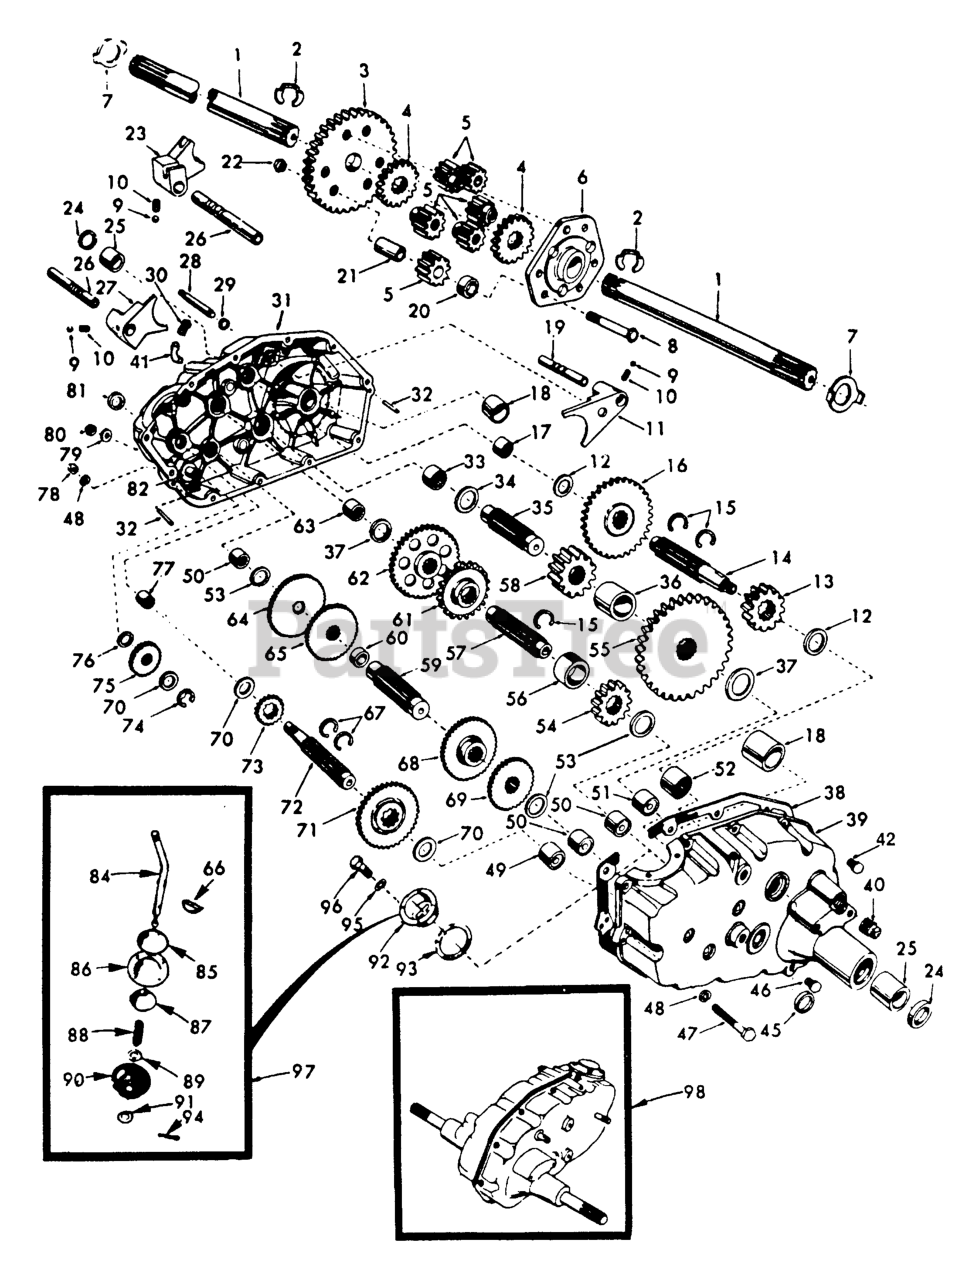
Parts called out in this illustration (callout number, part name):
1	AXLE SHAFT T
2	Retaining, Ring
3	FINAL GEAR T
4	DIFF GEAR T
5	DIFF PINION T
6	DIFF CARRIER T
7	WASHER T
8	Hex, Bolt 3/8-24 x 3-1/4 (1" Thread Length)
9	STEEL BALL KIT
10	SPRING T
12	THRUST WASHER
13	RED PINION T
14	GEAR SHAFT T
15	SNAP RING T
16	GEAR T
18	BEARING
21	PINION RS
22	GRIPCO NUT
23	SHIFT FORK T
24	OIL SEAL STD
25	BRNG. T
26	SHAFT T
28	SHIFT SHAFT
29	SEAL.OIL.SHAFT.SHIFT.T
31	GEARCASE RH
33	NEEDLE BRNG T
34	WASHER RACE BEARING THRUST
35	GEAR SHAFT T
36	GEAR SPACER T
39	GEARCASE LH
40	Pipe Plug 1/2-14 N.P.T.
41	ELBOW STREET 90
42	Bolt, Hex 5/16-18 UNC x 1-5/8
47	HEX BOLT
48	LOCKWASHER
49	BEARING TI
50	NEEDLE BRNG T
51	NEEDLE BRNG T
52	BEARING STD
53	BRNG RACE T
54	RED PINION T
55	RED GEAR T
56	PINION SPACER T
57	GEAR SHAFT T
58	FINAL PINION T
59	GEAR SHAFT T
61	RED PINION T
62	RED GEAR T
64	LOW SPEED GEAR T
65	GEAR.REVERSE.T
67	RING STD (1 2)
68	GEAR.SPEED.INTERMEDIATE.T/A
69	HIGH SPEED GEAR T
70	THRUST WASHER
71	CLUSTER GEAR T
72	INPUT SHAFT T
73	LO SPEED PINION T
74	RETAINING RING LT
75	IDLER GEAR T
78	NUT
80	NUT **
81	SEAL STD
82	SHAFT T
84	GEAR SHIFT LVR T
86	COVER AND PIN T
87	GUIDE BALL T
89	WASHER
90	SEAL.SHIFT
91	Washer 9/16 x 15/16 x 12 Ga.
92	GEAR SHIFT GATE T
94	COTTER PIN
95	WASHER.LOCK.HVY.HLCL.SPR.5/16
96	BOLT
97	GEAR SHFT LVR T
98	TRANSAXLE ASM
